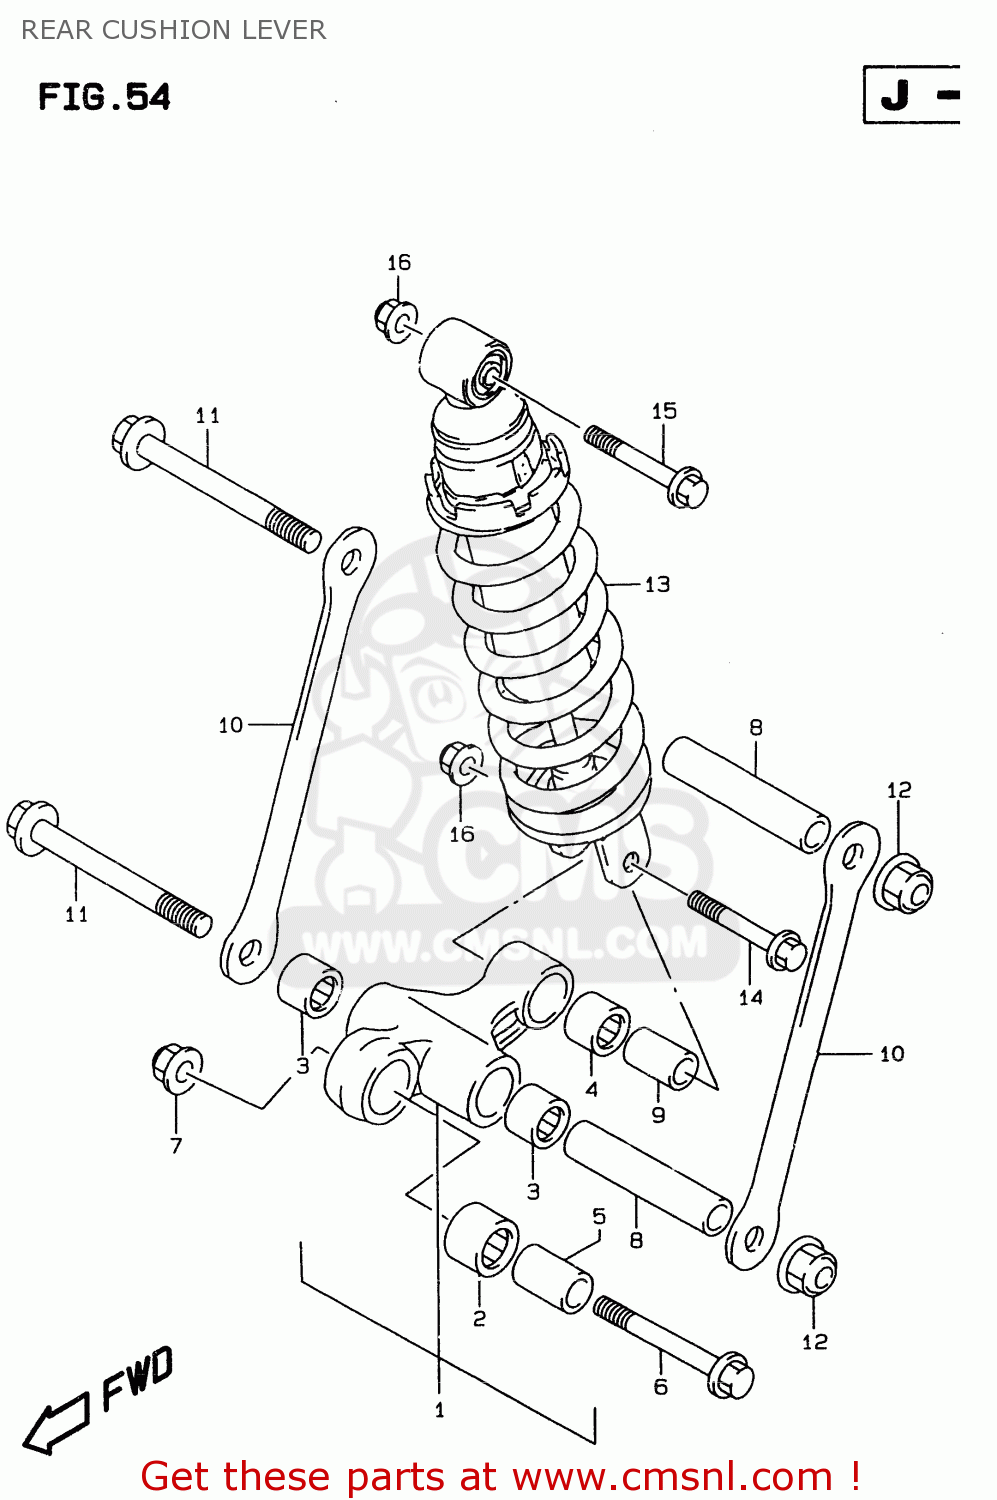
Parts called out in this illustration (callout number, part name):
1	LEVER SET,RR CUSHION
2	BEARING(20X27X26)
3	BEARING(17X24X25)
4	BEARING(17X24X26)
5	SPACER,RR CUSHION LEVER FR
6	BOLT,CUSHION LEVER FR
7	NUT 12MM
8	SPACER(12X17X85)
9	SPACER,RR CUSHION LEVER
10	ROD,RR CUSHION
11	BOLT(12X115)
12	NUT 12MM
13	ABSORBER ASSY,RR SHOCK
14	BOLT(10X54)
15	BOLT(10X50)
16	NUT
